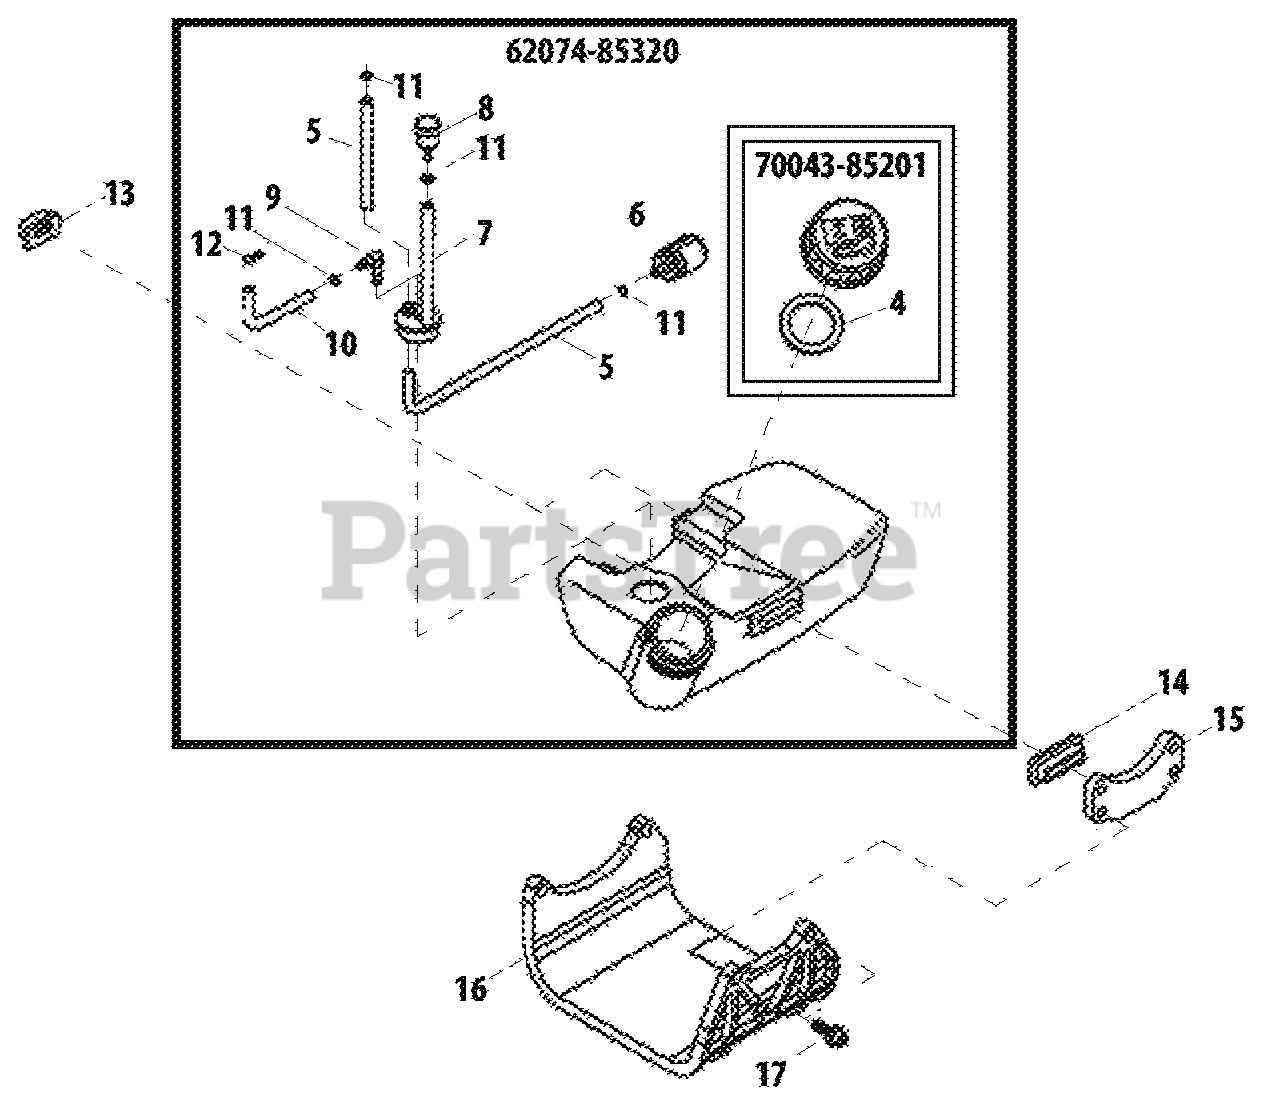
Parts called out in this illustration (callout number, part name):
4	GASKET, FUEL CAP
5	PIPE, FUEL
6	FILTER, FUEL
7	GROMMET
8	VENT ASSY
9	CONNECTOR, PIPE
10	PIPE, FUEL RETURN
11	CLIP Ø6
12	CLIP, SPRING Ø5.2
13	CUSHION, FUEL TANK
14	CUSHION, FUEL TANK - REAR
15	BRACKET, FUEL TANK
16	GUARD, FUEL TANK
17	BOLT M5×20
6207485320	FUEL TANK ASSY
7004385201	CAP ASSY, FUEL
